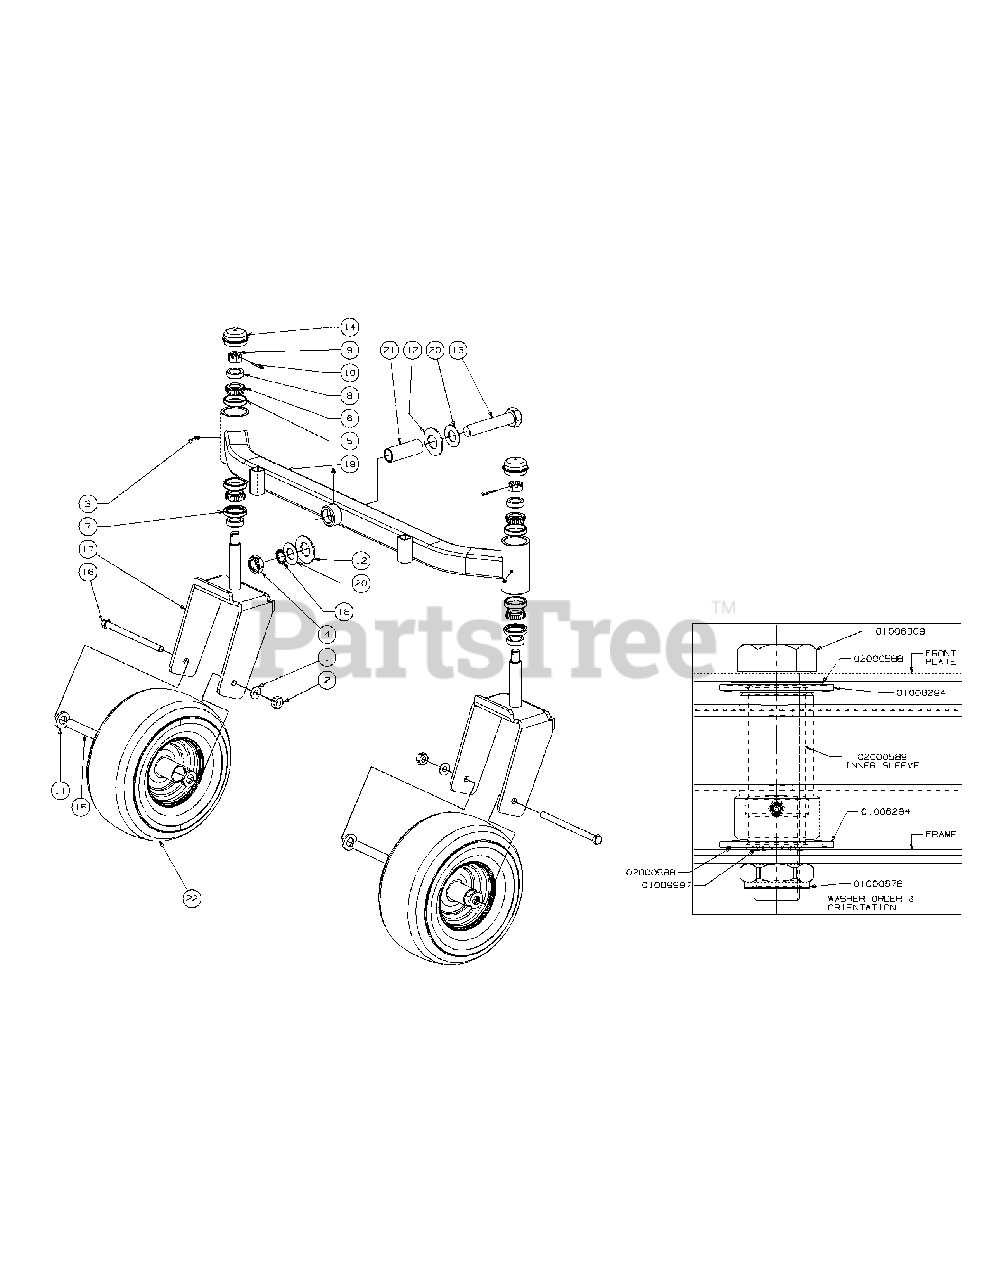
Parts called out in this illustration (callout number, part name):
1	Washer, 1/2 x 1 Shim
2	Nut, 1/2-20, Center Lock
3	Grease Fitting, 1/4-28 x 3/16
4	Nut, Jam, 1.0-14, Insert Lock
5	Cup Bearing
6	Bearing Cone
7	Seal
8	Ring Seal
9	Slotted Nut, 3/4-16
10	Cotter Pin, 5/32, 1.25
11	Spacer, .812 ID x .218LG
12	Bell Washer, 1.25 ID x 2.5 x .157
13	Hex Cap Screw, 1-14 x 5.0
14	Grease Cap, 1.986 OD
15	Wheel Spacer
16	HHCS, 1/2-20, 7.50
17	Yoke, Caster Wheel
18	Retainer Extension, Self Locking
19	Front Axle Assembly
20	Flat Washer, 1.00 ID
21	Spacer, 1.005 ID x 1.25 OD x 3.6
22	Wheel, 13 x 6.50 x 6.0, Beige, includes:
22	Roller Bearings (per tire)
22	Retainer Bushings (per tire)
